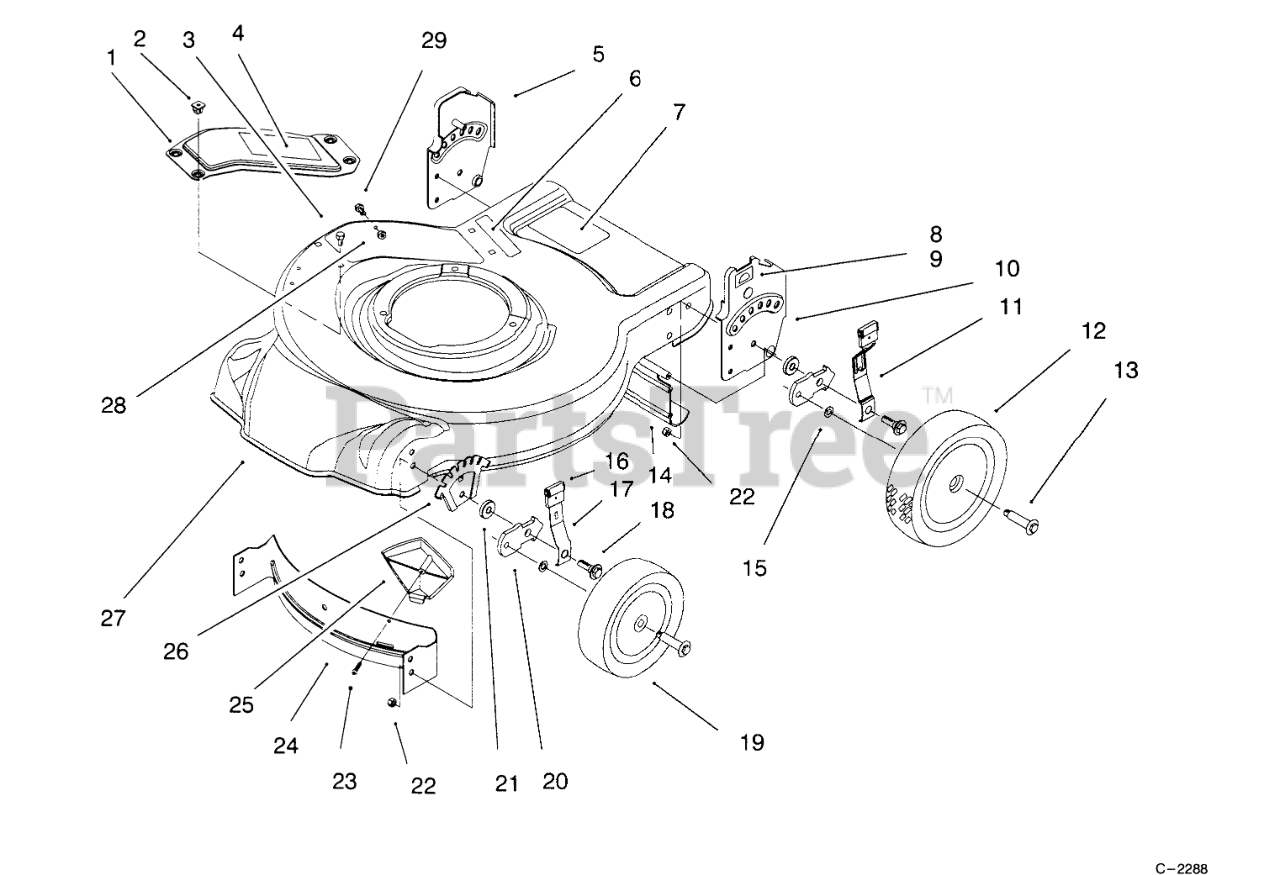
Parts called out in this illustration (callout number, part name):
1	Cover-Recycling (Incl. Ref. #4)
2	NUT - CLIP
3	SCREW-HWH
4	DECAL - COVER
5	ASM - RH HANDLE BRACKET
6	DECAL - WARNING
7	DECAL-WARNING
8	DECAL-HOC, RH
9	DECAL-HOC, LH
10	ASM - LH HANDLE BRACKET
11	REAR SPRING ARM ASM
12	WHEEL ASM
13	BOLT-SHOULDER
14	SHIELD-TRAILING
15	WASHER
16	KNOB-LEVER, HEIGHT ADJUSTMENT
17	ARM-FRONT SPRING
18	BOLT-SHOULDER
19	WHEEL ASM
20	Bracket-H.
21	WASHER
22	NUT-LOCK, NI
23	SCREW-PPH
24	Baffle Front
25	KICKER-FRONT
26	Plate H.O.C.
27	Deck Assembly (Incl. Ref. #6 & 7 pg. 1)(Incl. Ref. #14 pg. 2)
28	NUT-LOCK, NI
